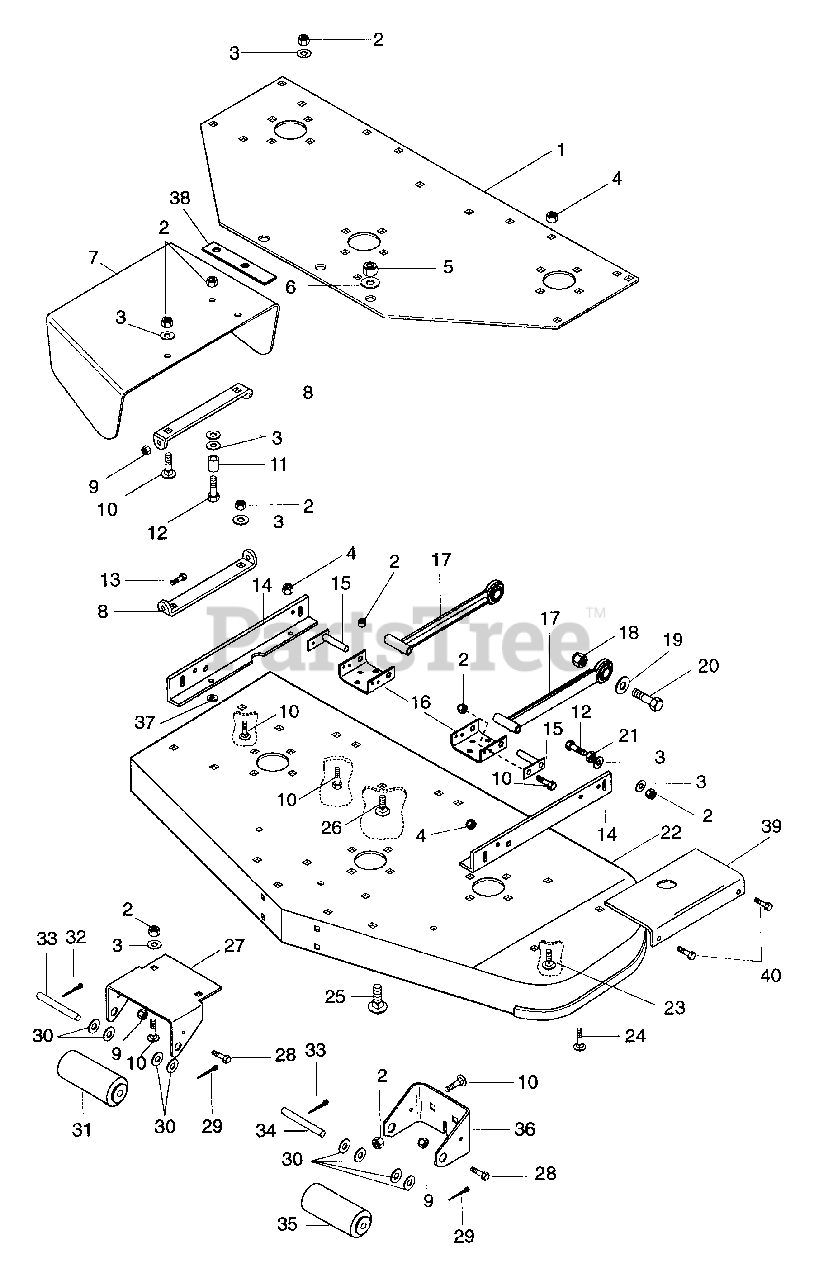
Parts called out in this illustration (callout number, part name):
1	Plate, Support
2	Nut-Locking-Nylon .375-16 Grade 2
3	Washer-Flat-Steel .406 x .812 x .065
4	Nut-Locking-Nylon .312-18 Grade 2
5	Nut-Locking-Nylon .50-13 Grade 2
6	Washer-Flat-Steel .531 x 1.250 x .100
7	Shield, Safety External 50" Mower
8	Bracket, Chute
9	Nut-Locking-Nylon .250-20 Grade 2
10	Bolt-Round Head Square Neck .38-16 x 1.0
11	Bushing-Sleeve .407 x .625 x .750
12	Bolt-Hex .38-16 x 1.50 Grade 5
13	Bolt-Hex .25-20 x .875
14	Bracket, 50" Mower Mounting L.H.
14	Bracket. 50" Mower Mounting R.H.
15	Weldment, Mower Mounting Pin
16	Bracket, Mower Mounting Rear
17	Weldment, Mower Mounting Arm
18	Nut, Locking .875-9
19	Washer Flat-Steel .875 x 1.500 x .1196
20	Bolt-Hex .87-9 x 2.75 Grade 5
21	Nut-Hex .375-16 Grade 2
22	Weldment, 50" Mower Fabricated
23	Bolt-Round Head Square Neck .31-18 x .62
24	Bolt-Round Head Square Neck .31-18 x 1.0
25	Bolt-Round Head Square Neck .50-13 x 1.00
26	Bolt-Round Head Square Neck .375-16 x .75 Grade 1
27	Bracket, Roller R.H.
28	Bolt-Hex .25-20 x .75 Grade 5
29	Pin-Cotter .250 x 2.00
30	Washer-Flat-Steel .656 x 1.312 x .095
31	Roller, Gage
32	Pin-Cotter .25 x 1.00
33	Shaft, Center Roller
34	Rod
35	Roller, Gage
36	Bracket, Roller
37	Bushing .406 x .750 x .188
38	Limiter, Disch. Chute
39	Guard, Mower Belt
40	Bolt-Hex .31-18 x .75 Grade 5
